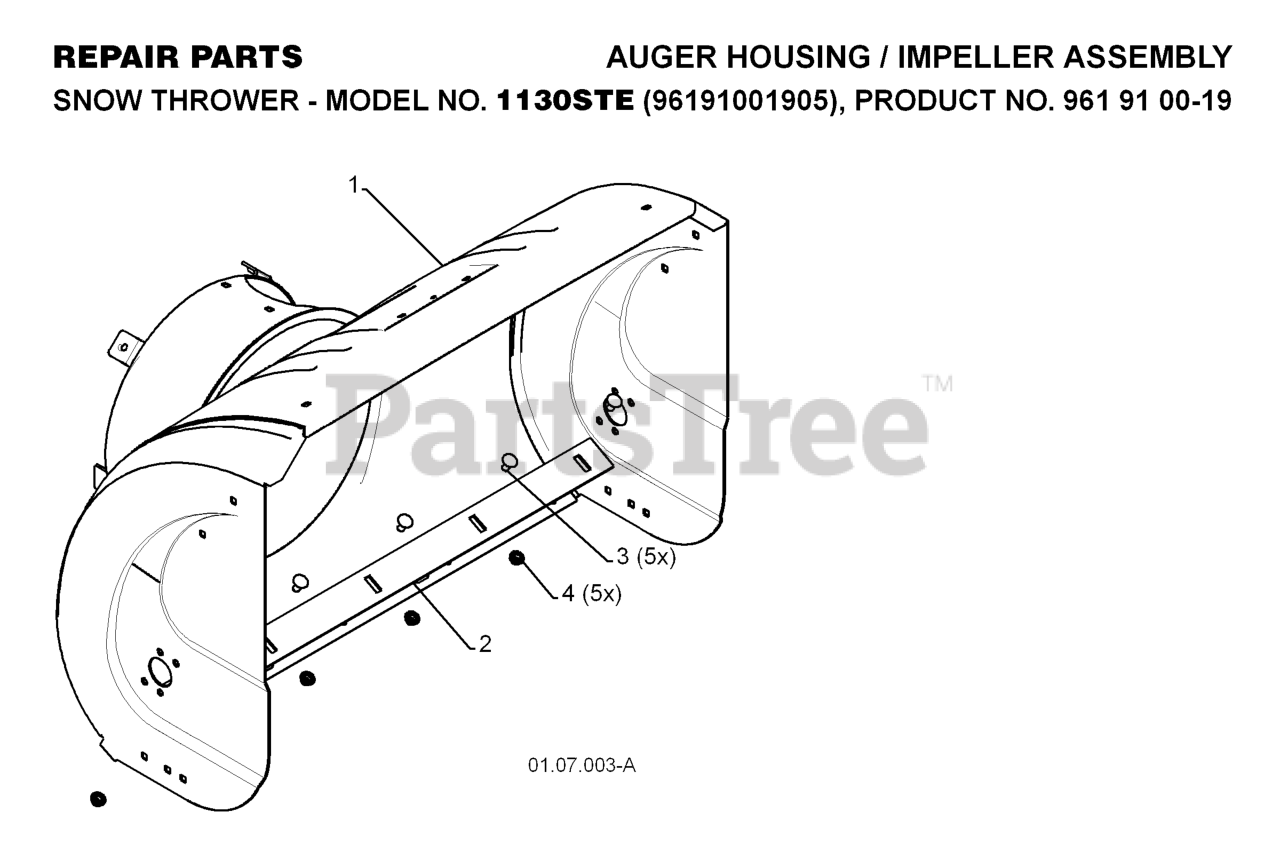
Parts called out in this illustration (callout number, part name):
1	HOUSING, AUGER
2	BAR, SCRAPER
3	BOLT
4	NUT.FLANGE.5/16
